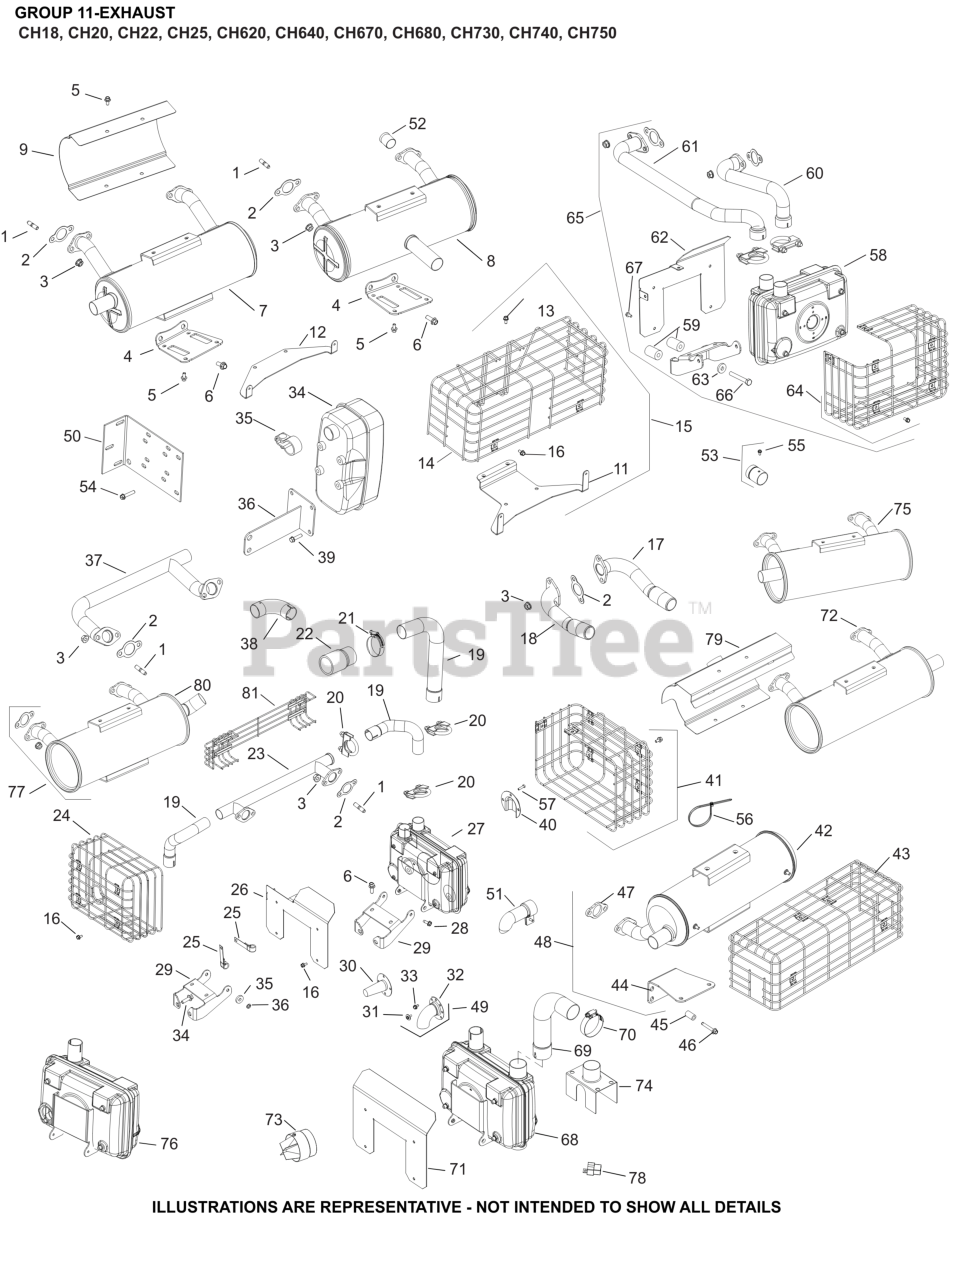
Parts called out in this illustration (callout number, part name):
1	STUD, METRIC EXHAUST
2	GASKET, EXHAUST
3	NUT, FLG M8X1.25
6	SCREW, FLG M8X1.25X20
44	BRACKET, MUFFLER
45	SPACER .281 X .500 X .875
46	SCREW, FLG M6X1.0X40
